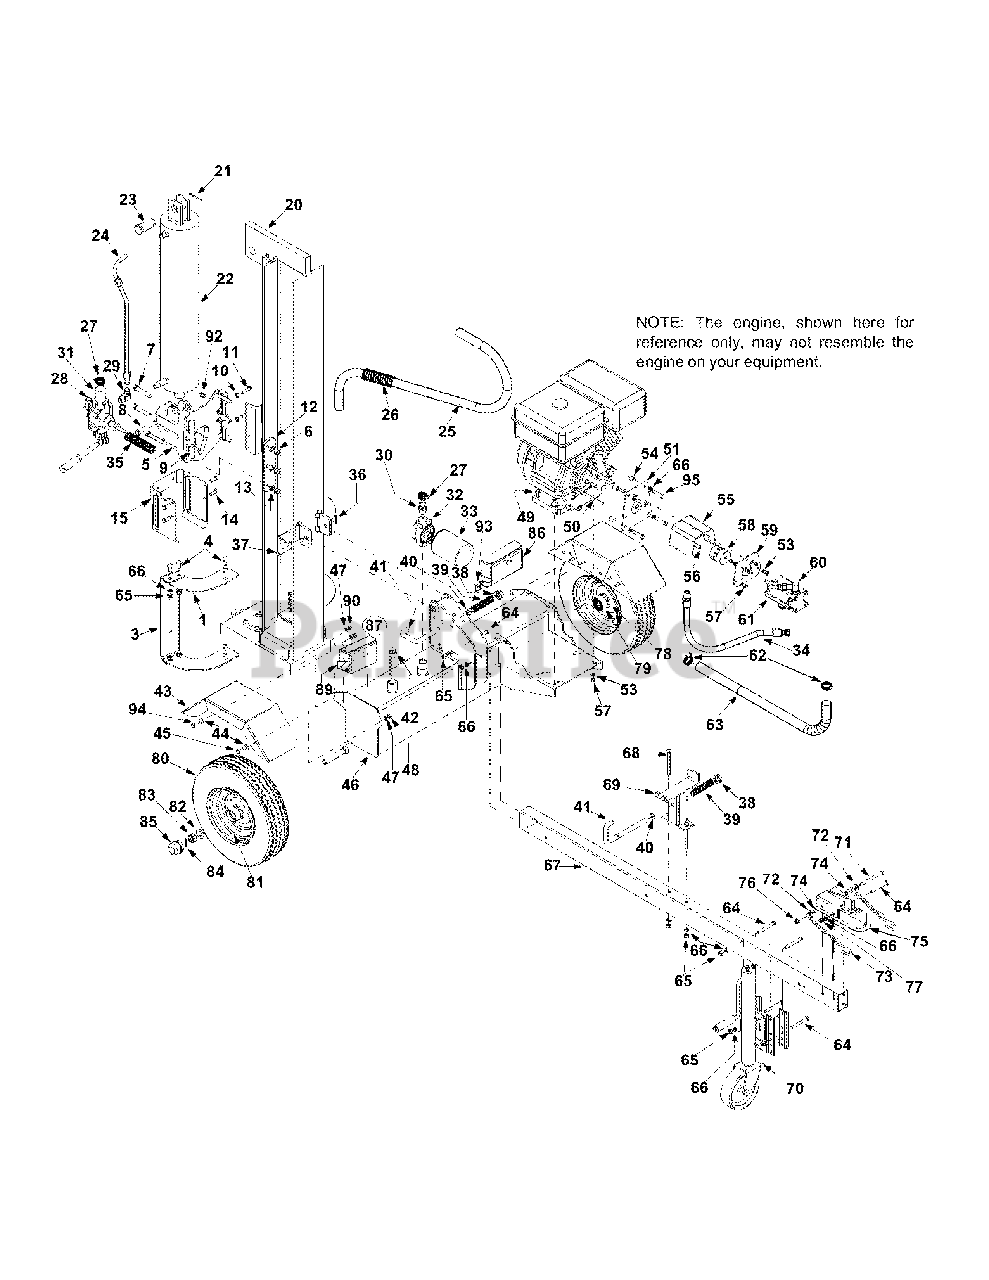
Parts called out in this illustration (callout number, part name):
4	Carriage Bolt 3/8-16 x 1.0
5	Wedge Assembly
6	Lock Nut 1/2-20
7	Hex Cap Screw 1/2-20 x 2.75
8	Hex Screw 1/2-13 x 3.25
9	Adjustable Gib
10	Hex Jam Nut 3/8-24
11	Hex Cap Screw 3/8-24 x 1.5
13	Lock Washer 1/2
14	Flat Washer .406 ID x .875 OD
20	Beam Assembly
21	Cotter Pin
23	Clevis Pin
24	Hydraulic Tube
25	Return Hose 3/4" ID x 44" Lg.
26	Hose Guard
27	Hose Clamp 5/8"
28	Return Elbow
29	90 Degree Solid Male Adapter
30	3/4" Hose Adapter
32	Filter Housing
33	Oil Filter
34	High Pressure Hydraulic Hose
35	Hose Guard
36	Cotter Pin 1/8"
37	Hinge Pin 1/2 x 4.8" Lg.
39	Compression Spring 4"
40	Flat Washer .635 ID x .93 OD
41	Locking Rod
42	Vented Dipstick
44	Lock Washer 5/16
45	Hex Screw
46	Frame Assembly 7.0 Gal
47	Lock Washer 5/16
48	Hex Nut 5/16-24
49	Hex Cap Screw 5/16-24 x 1.75
50	Hex Cap Screw 5/16-24 x 5.25
54	Hex Cap Screw 5/16-24 x .625
55	Shoulder Spacer
56	Key
57	Hex Screw 5/16
58	Flex Coupling, 1.0 x .4375 "Stamped L090"
58	Coupling Half, 1.00
58	Coupling Half, .500
58	Spider Bushing
60	Adapter 7/8-14
61	Pump (16 gmp)
61	Pump (15 gmp) Service Kit
61	Pump (15 gmp)
62	Hose Clamp
63	Suction Hose
64	Hex Cap Screw 3/8-16 x 3.0
65	Hex Nut 3/8-16
66	Lock Washer 3/8
68	Hex Cap Screw 3/8-16 x 4.0
71	Hex Cap Screw 3/8-16 x 4.25
72	Flat Washer .385 ID x .870 OD
73	Chain
75	Hitch Coupler
76	Lock Nut 3/8-16
77	Hex Jam Nut 3/8-16
78	Bearing Seal
79	Bearing Cone
80	Wheel Assembly
82	Flat Washer .76" ID x 1.5" OD
83	Slotted Nut 3/4-16
84	Cotter Pin 5/32" x 1-1/4" Lg.
92	Lock Nut 1/2-13
